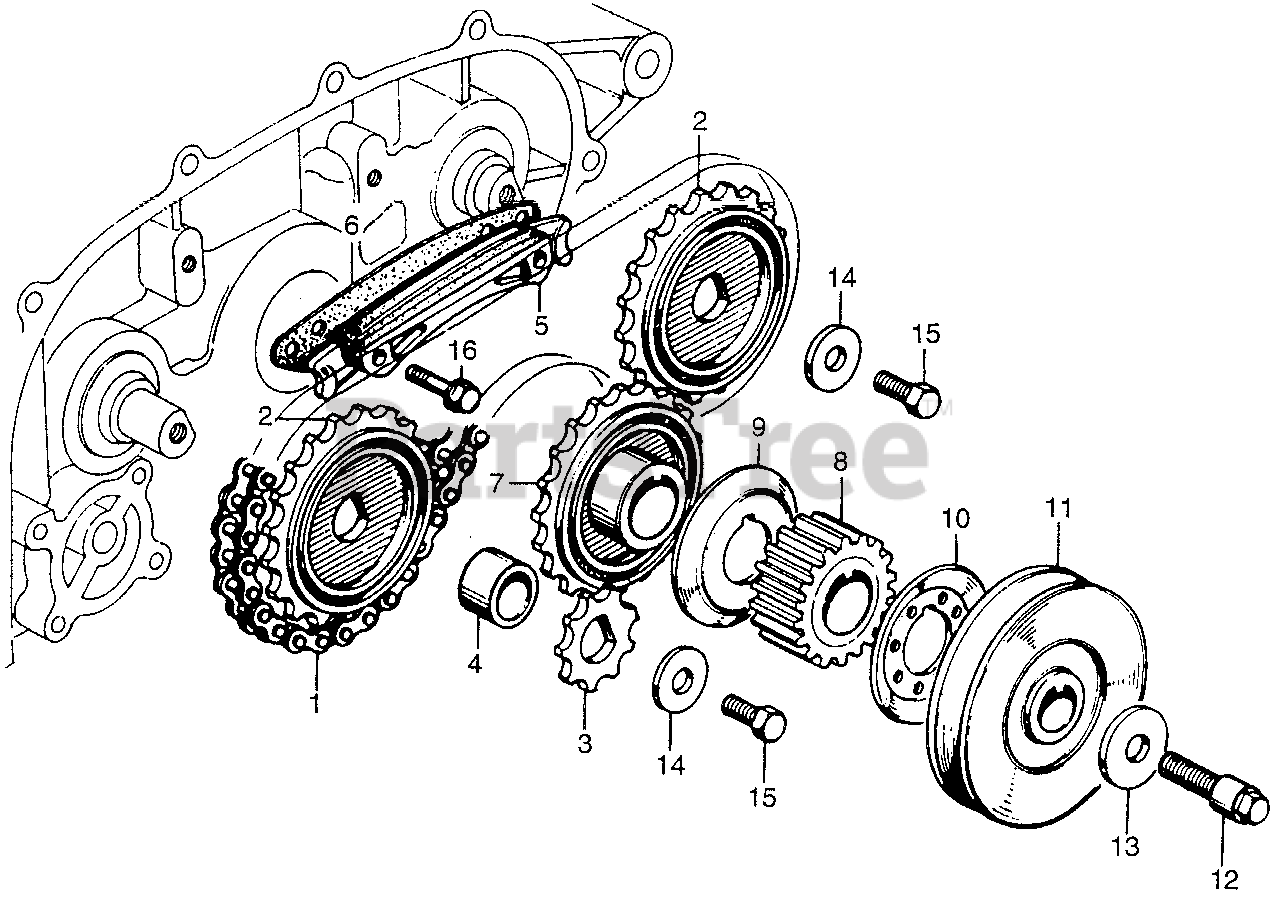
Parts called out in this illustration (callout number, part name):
1	CHAIN, BALANCER
2	SPROCKET, BALANCER DRIVEN
3	SPROCKET, OIL PUMP DRIVE
4	COLLAR, FR. BALANCER SHAFT
5	SLIPPER, BALANCER CHAIN
6	GASKET, BALANCER CHAIN SLIPPER
7	SPROCKET, BALANCER DRIVE
8	PULLEY, TIMING BELT DRIVE
9	PLATE A, TIMING BELT GUIDE
10	PLATE B, TIMING BELT GUIDE
11	PULLEY, CRANKSHAFT
12	BOLT, SPECIAL (10X25)
13	WASHER, SPECIAL (34X10.5X4.0)
14	WASHER, SPECIAL (22X8.5X2)
15	BOLT, HEX. (8X12)
16	BOLT, FLANGE (6X25)
